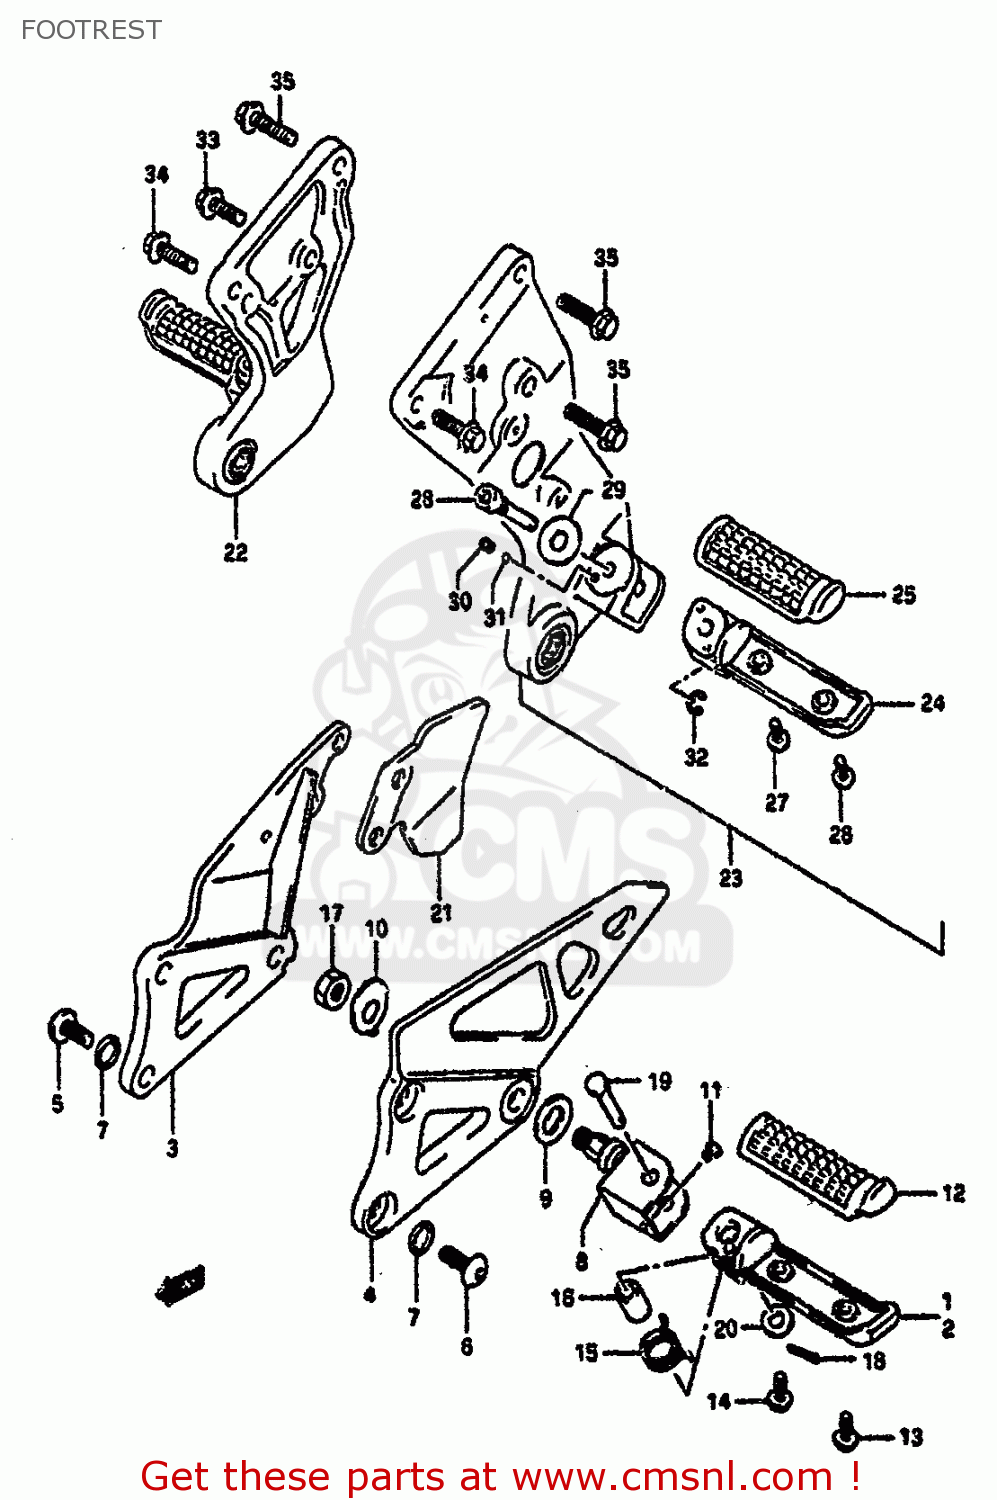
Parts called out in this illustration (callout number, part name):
1	BAR,FOOTREST,R
2	BAR,FOOTREST,L
3	BRACKET,FOOTREST,R
4	BRACKET,FOOTREST,L
5	BOLT,FOOTREST BRACKET
6	BOLT,FOOTREST BRACKET
7	WASHER
8	HOLDER,FOOTREST,RIGHT
9	PLATE,FOOTREST INNER
10	WASHER,FR FOOTREST
11	CUSHION,FOOTREST
12	RUBBER,FOOTREST
13	SCREW
14	SCREW
15	SPRING
16	SPACER(8.1X12X22)
17	NUT 12MM
18	PIN 20X15
19	PIN
20	WASHER(8.5X18X1)
21	GUARD,FRONT FOOTREST,RIGHT
22	FOOTREST ASSY,PILLION,R
23	FOOTREST ASSY,PILLION,L
24	BAR,PILLION FOOTREST,L
25	RUBBER,FOOTREST
26	SCREW
27	SCREW
28	BOLT,PILLION FOOTREST
29	WASHER
30	SPRING
31	BALL
32	E RING 6MM
33	BOLT
34	BOLT
35	BOLT
